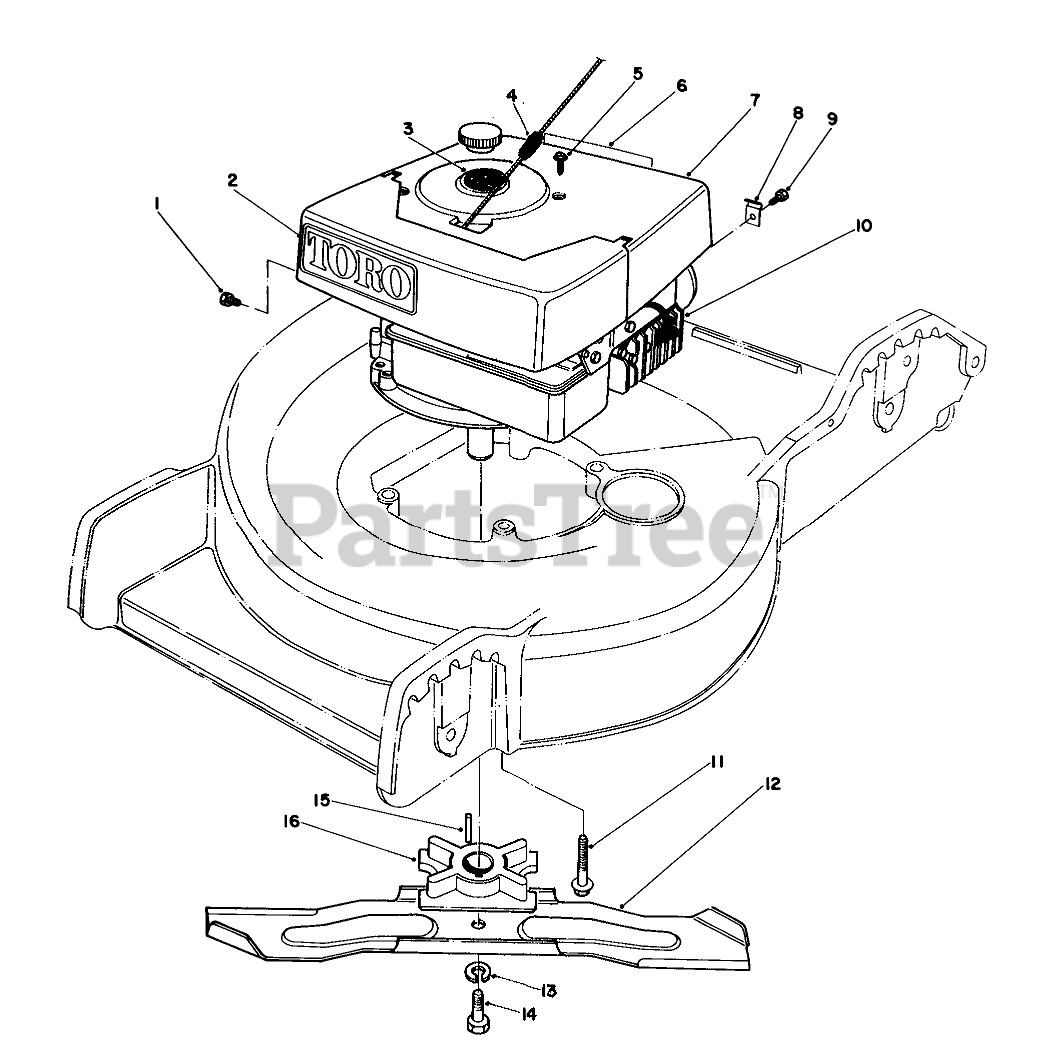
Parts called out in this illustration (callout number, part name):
1	SCREW-HH
2	Decal Tow
3	Decal-Shroud
4	ROPE STOP
5	TAPPING SCREW
6	Decal-Danger
7	Shroud-Assembly
9	Screw-Clamp
10	Engine
11	3/8-16 X 2 CAPSCREW
12	Blade
13	WASHER-LOCK
14	SCREW-HH
15	KEY-SQUARE
16	Blade Retainer
